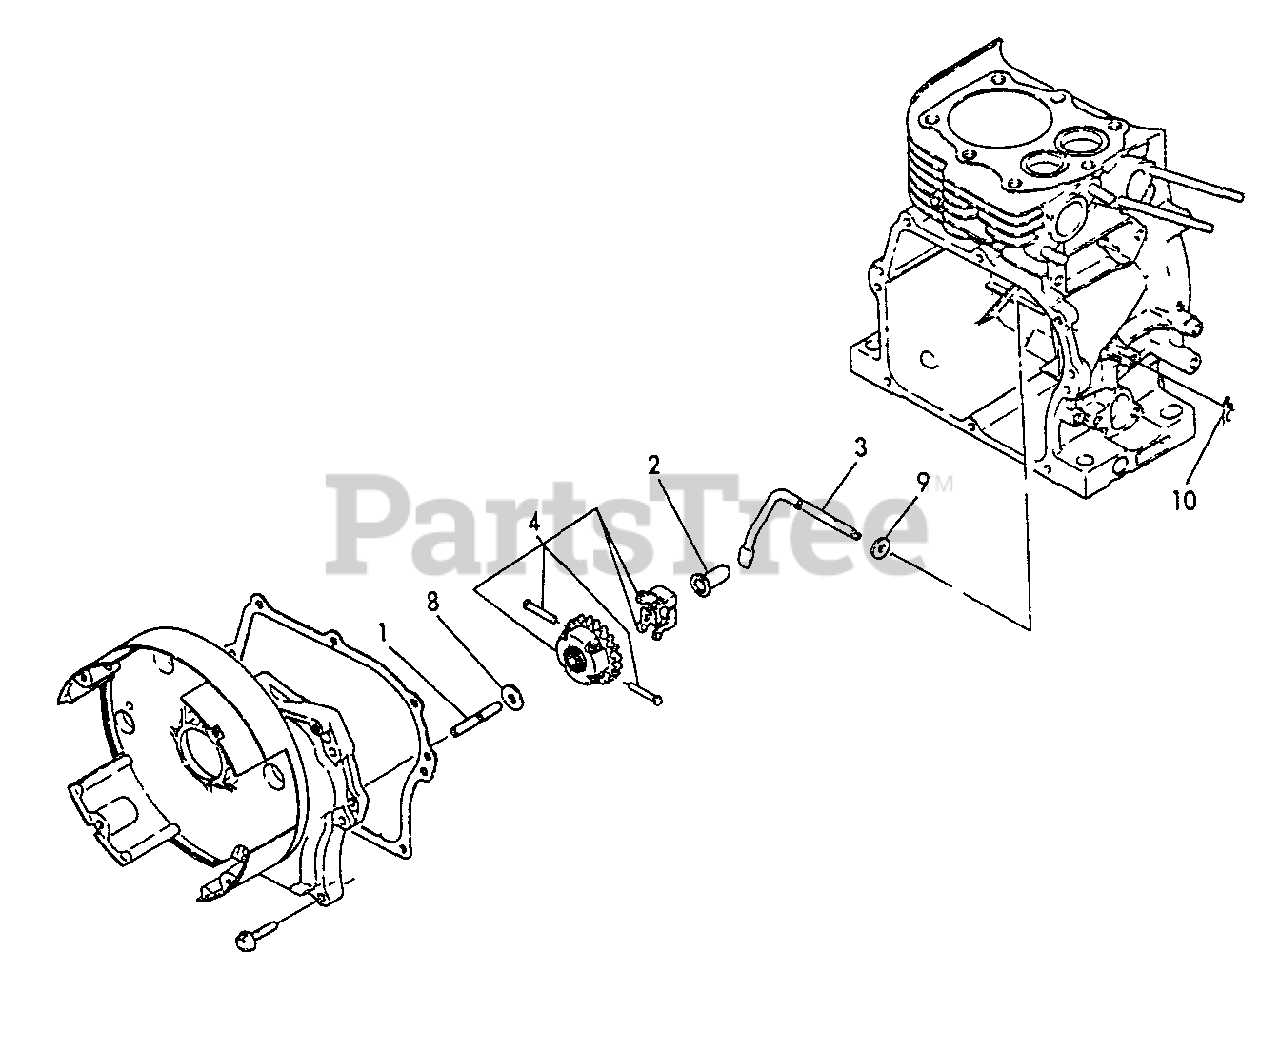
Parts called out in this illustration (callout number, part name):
1	SHAFT, GOVERNOR
2	SPINDLE, GOVERNOR
3	YOKE
4	GOVERNOR GEAR ASSY
8	WASHER
9	WASHER - 6
10	PIN - 6 -- SNAP
